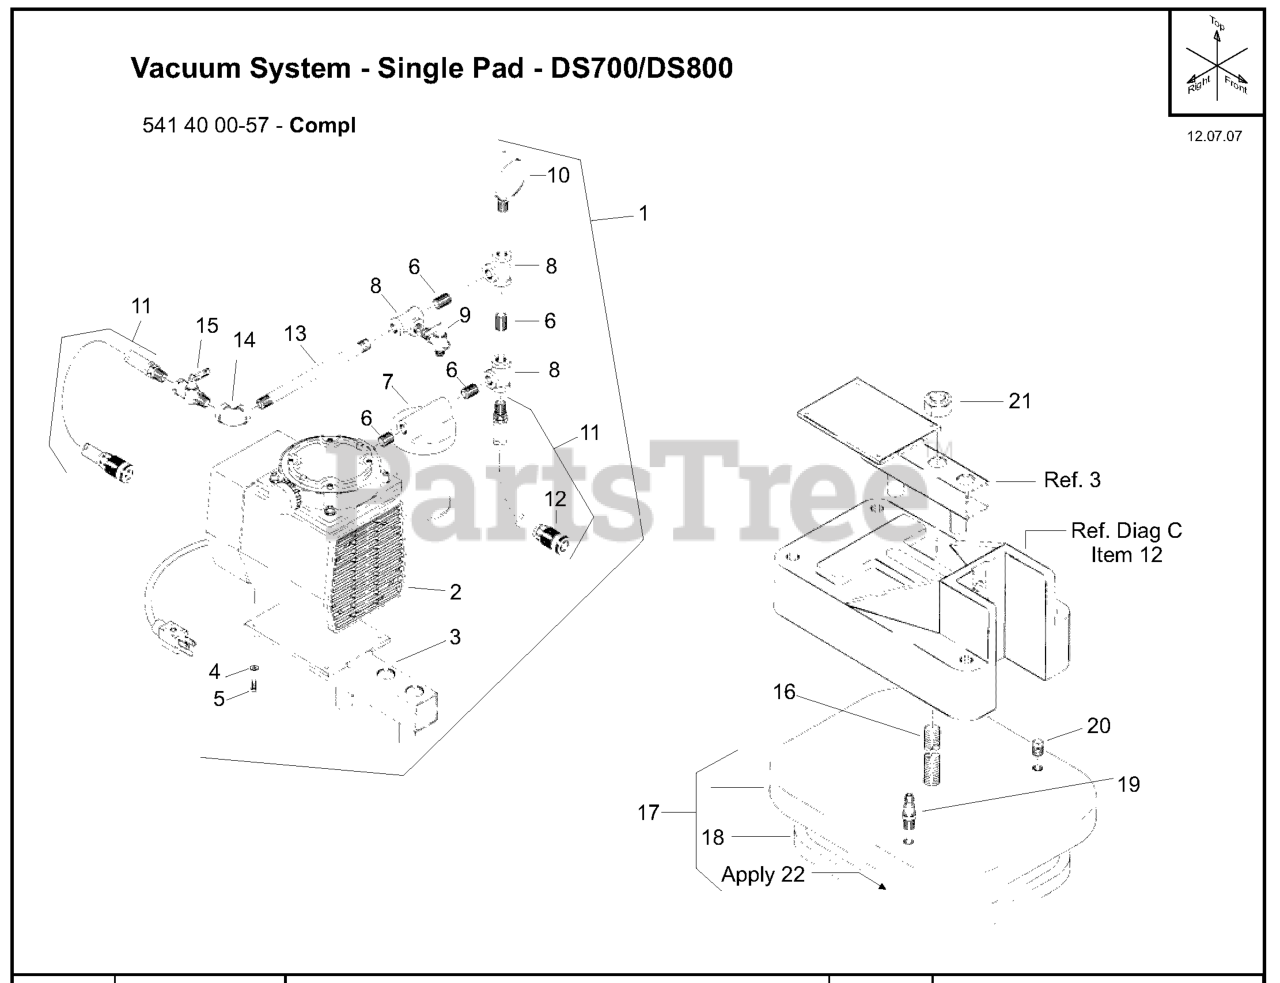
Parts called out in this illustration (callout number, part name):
1	Vacuum Pump Assy
2	Pump, Vacuum
3	Frame - Vacuum Pump
4	Washer, Flat 1/4 SAE
5	Capscrew, Soc Hd 10-32 x 1/2
6	Pipe Fit., Nipple 1/4 NPT x Close - Galv
7	Trap, Water
8	Pipe Fit., Female Tee 1/4 NPT - Galv
9	Valve, Release 1/4 NPT
10	Gauge, Vacuum
11	Hose Assy
12	Body, Quick Disconnect, 1/4 PL
13	Pipe Fit., Nipple 1/4 x 7 Galv
14	Pipe Fit., 90 Deg Fem Elbow 1/4 NPT - Galv
15	Valve Shut-Off - Single Pad
16	Stud, Pad 3/4-10 x 8"
17	Pad, Vacuum
18	Gasket, Rubber
19	Stem, Quick Disconnect
20	Pipe Fit., Plug 1/4 NPT
21	Nut, Hex 3/4-10
22	Adhesive, Tube - 5 OZ
